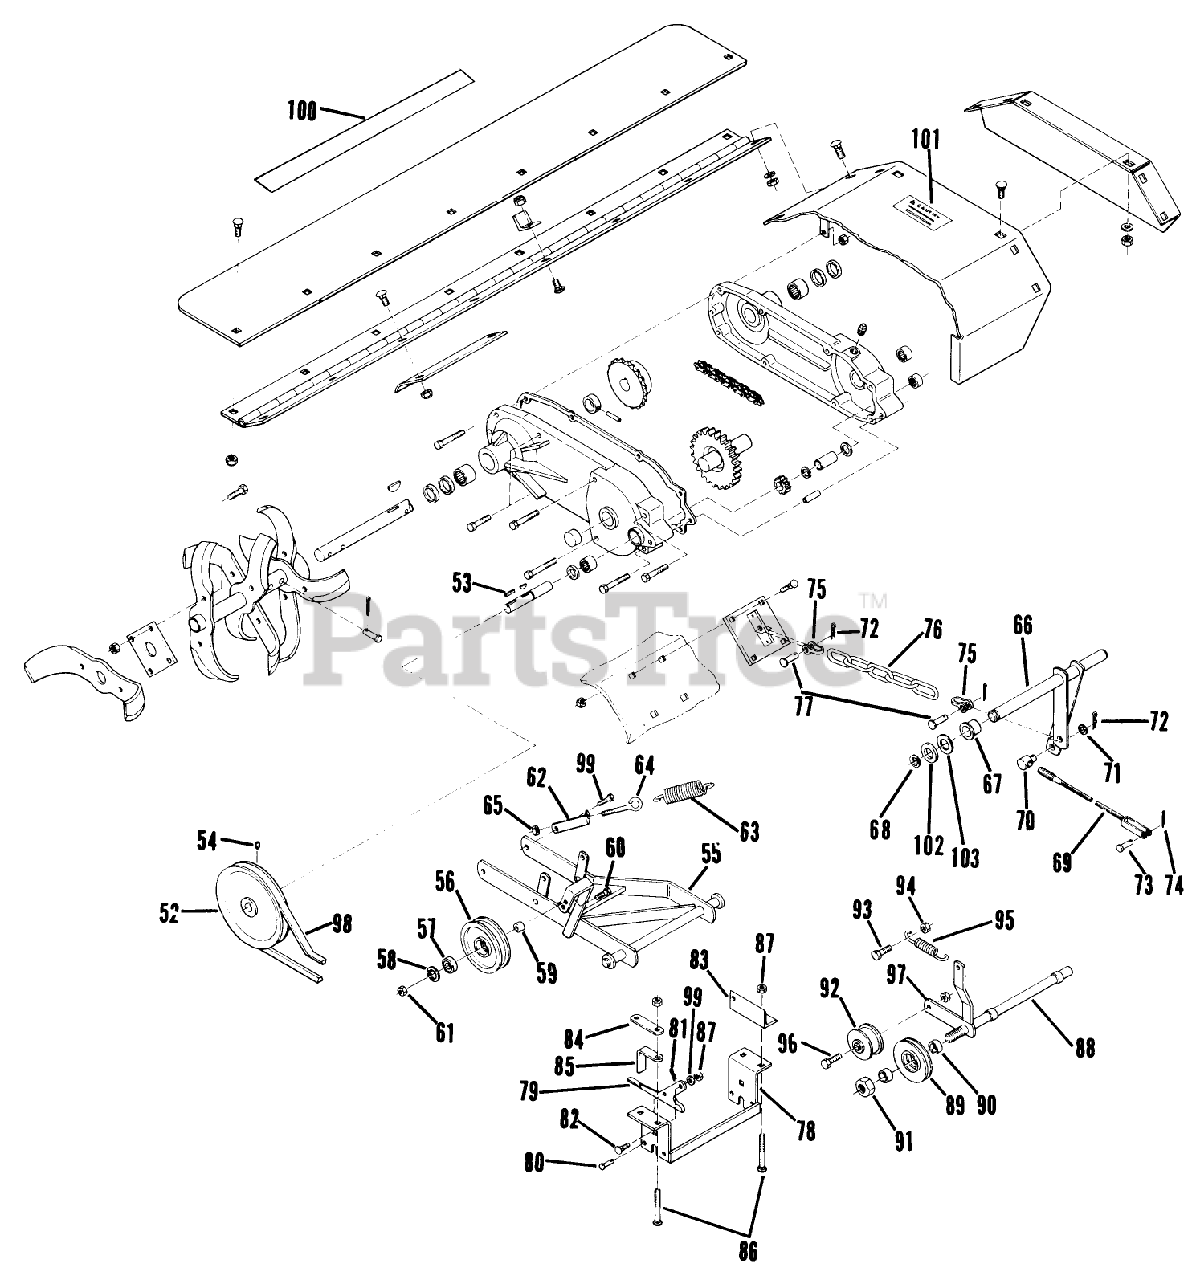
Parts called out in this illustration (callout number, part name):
51	WASHER 5/16 SAE
52	Pulley
53	KEY-STRAIGHT
54	Setscrew-Square Head
55	Hitch
56	PULLEY IDLER
57	BEARING
58	INTERNAL SNAPRING
59	SPACER
60	HEX HD CAP SCREW
61	Nut
62	Bracket-Spring
63	SPRING
64	EYEBOLT
65	NUT
66	Lever Assy.
67	BUSHING
68	E-RING
69	ASSY-LIFT CABLE
70	TRUNNION-CLUTCH ROD
71	Washer
72	Hairpin
73	Pin
74	Cotter Pin
75	Clevis
76	CHAIN-LIFT
77	Clevis Pin
78	Bracket
79	PLATE-LATCHING
80	Pin
81	Hairpin
82	Bolt
83	Link
84	BRACKET-REAR LINK MOUNTING
85	SPACER-BRACKET
86	Bolt-Carriage
87	Nut
88	Front Idler
89	Pulley-V
90	Spacer
91	Nut
92	IDLER PULLEY
93	BOLT
94	Nut
95	SPRING-BRAKE
97	Nut
98	V BELT
99	Washer
100	DECAL-WHEEL HORSE
101	Caution Decal
102	WASHER
103	WASHER-SHIM
